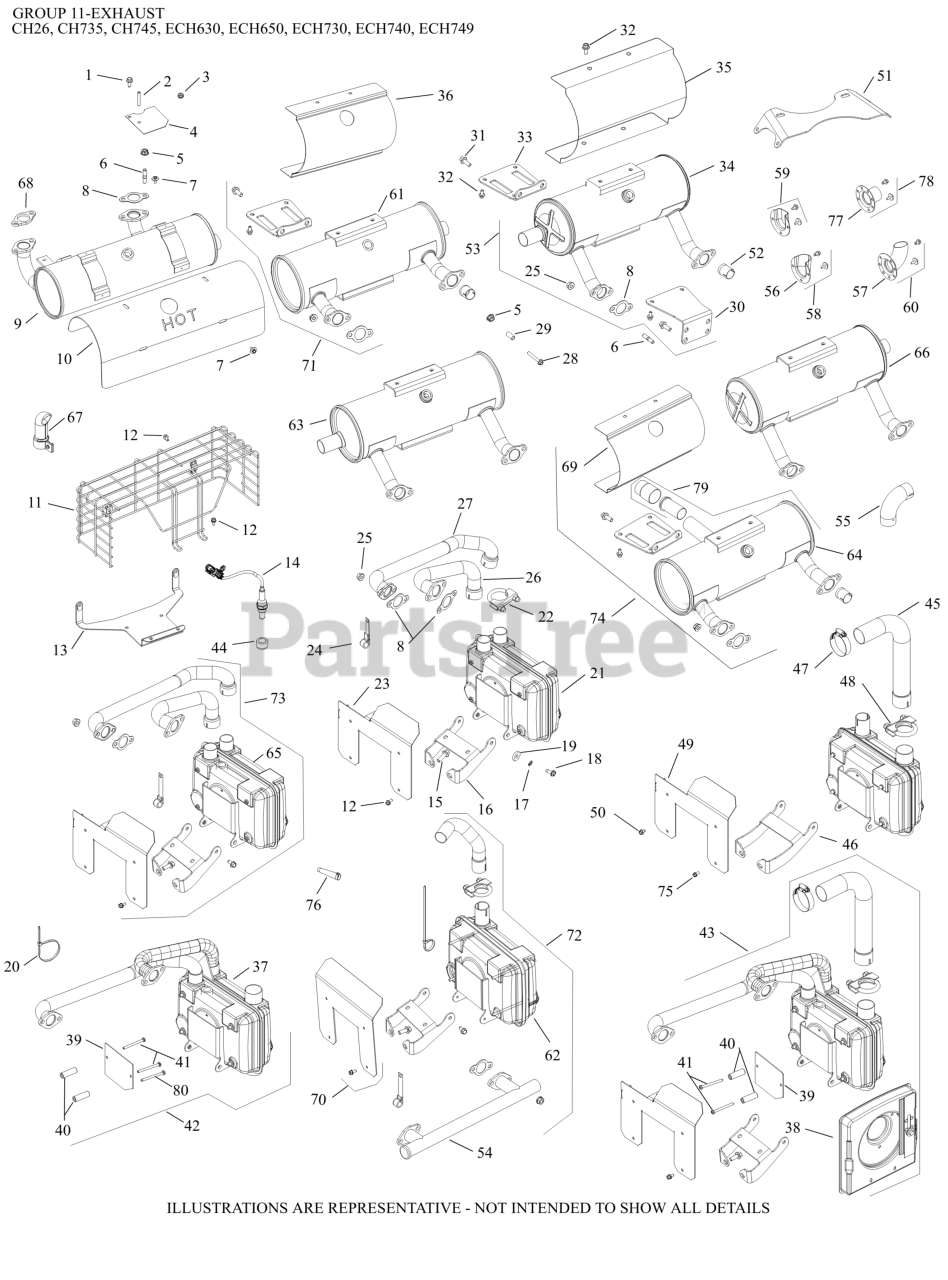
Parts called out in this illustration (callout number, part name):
8	GASKET, EXHAUST
14	SENSOR, OXYGEN
25	NUT, FLG M8X1.25
31	SCREW, FLG M8X1.25X20
32	SCREW, FLG M6X1.0X12
33	BRACKET, MUFFLER
35	SHIELD, HEAT
52	LINER, EXHAUST PORT
53	MUFFLER KIT, FILTER SIDE/STRAIGHT
